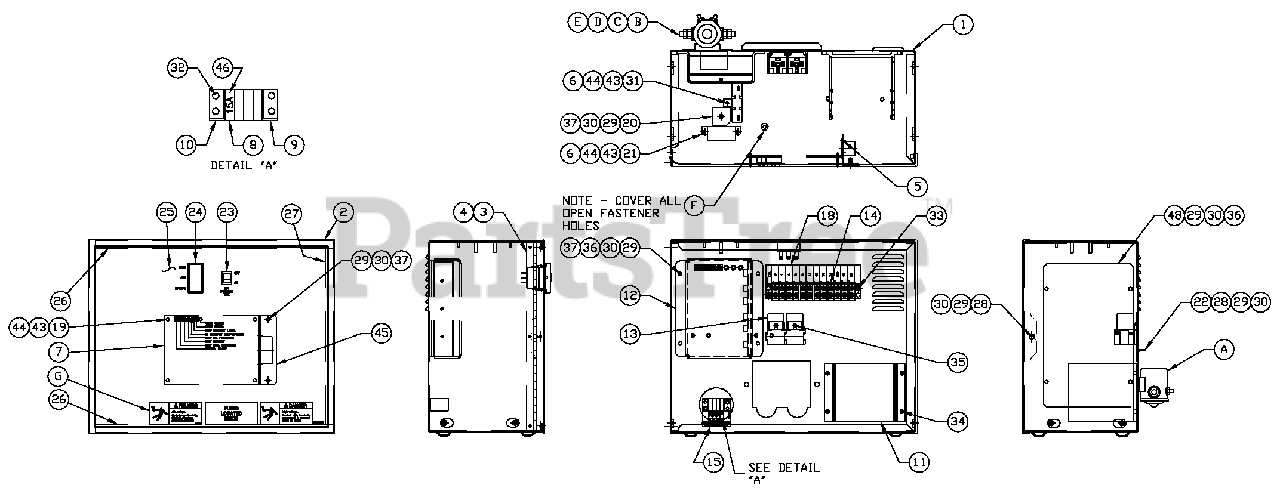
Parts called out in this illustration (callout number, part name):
1	ENCL HSB CONTROL PANEL
2	COVER CONTROL PANEL
3	HINGE CONTINUOUS H-PANEL
4	RIVET POP.125X .275 SS
5	SCREW PPPH HI-LO#4-24 X 3/8
6	WASHER FLAT M3
7	ASSY PCB R-200 3600 RPM
8	HOLDER FUSE WICKMANN 178.6150
9	ADPTR RH SIDE WICKMAN 178.61591
10	ADPTR LH SIDE WICKMAN 178.6192
11	ASSY PCB 2AMP 12V ULBATT CHGR
12	ASSY VOLTAGE REGULATOR 60HZ
13	RELAY 12VDC C FORM W/DIODE
14	BLOCK TERM 20A 12X6X1100V
15	DECAL CPL CONTROL PANEL FUSES
18	DECAL CPL 3.9L TB1
19	SPACER 9.5H 3.2 ID
20	DIO BRIDGE 25A 600V
21	CIRCT BRK 4 X 1 ETA 46-500-P
22	PLATE HARNESS CLAMP
23	SWITCH RKR DPST 125V SPD
24	SWITCH RKR DPDT ON-OFF-ON
25	DECAL CONTROL HSB
26	SEAL COVER 3.18 X 12.7 X 382
27	SEAL COVER 3.18 X 12.7 X 283
28	SCREW HHPM M5-0.8 X 12
29	WASHER FLAT M5
30	WASHER LOCK M5
31	RES WW 15R 5% 25W QK CONN
32	SCREW PHTT M3.5-0.6 X 10
33	SCREW PHTT M3.5-0.6 X 16
34	SCREW PHTT M4.0.7 X 12 ZYC
35	SCREW PHTT M4.0.7 X 10 ZYC
36	SCREW PPHM M5-0.8 X 12 ZNC
37	NUT HEX M5-0.8 G8 CLEAR ZINC
43	WASHER LOCK M3
44	NUT HEX M3-0.8 G8 YEL CHR
45	SUPPORT ANGLE PCB
46	FUSE ATO TYPE 15 AMP (BLUE)
48	PLATE COVER PANEL
A	DECAL DANGER HIGH VOLTAGE BI
B	SCREW HHC 1/4-20 X 3/4 G5
C	WASHER FLAT 1/4-M6 ZINC
D	WASHER LOCK M6-1/4
E	NUT HEX 1/4-20 STEEL
F	SEAL WEATHER .45"DIA
G	DANGER HIGH VOLTAGE (SPANISH)
